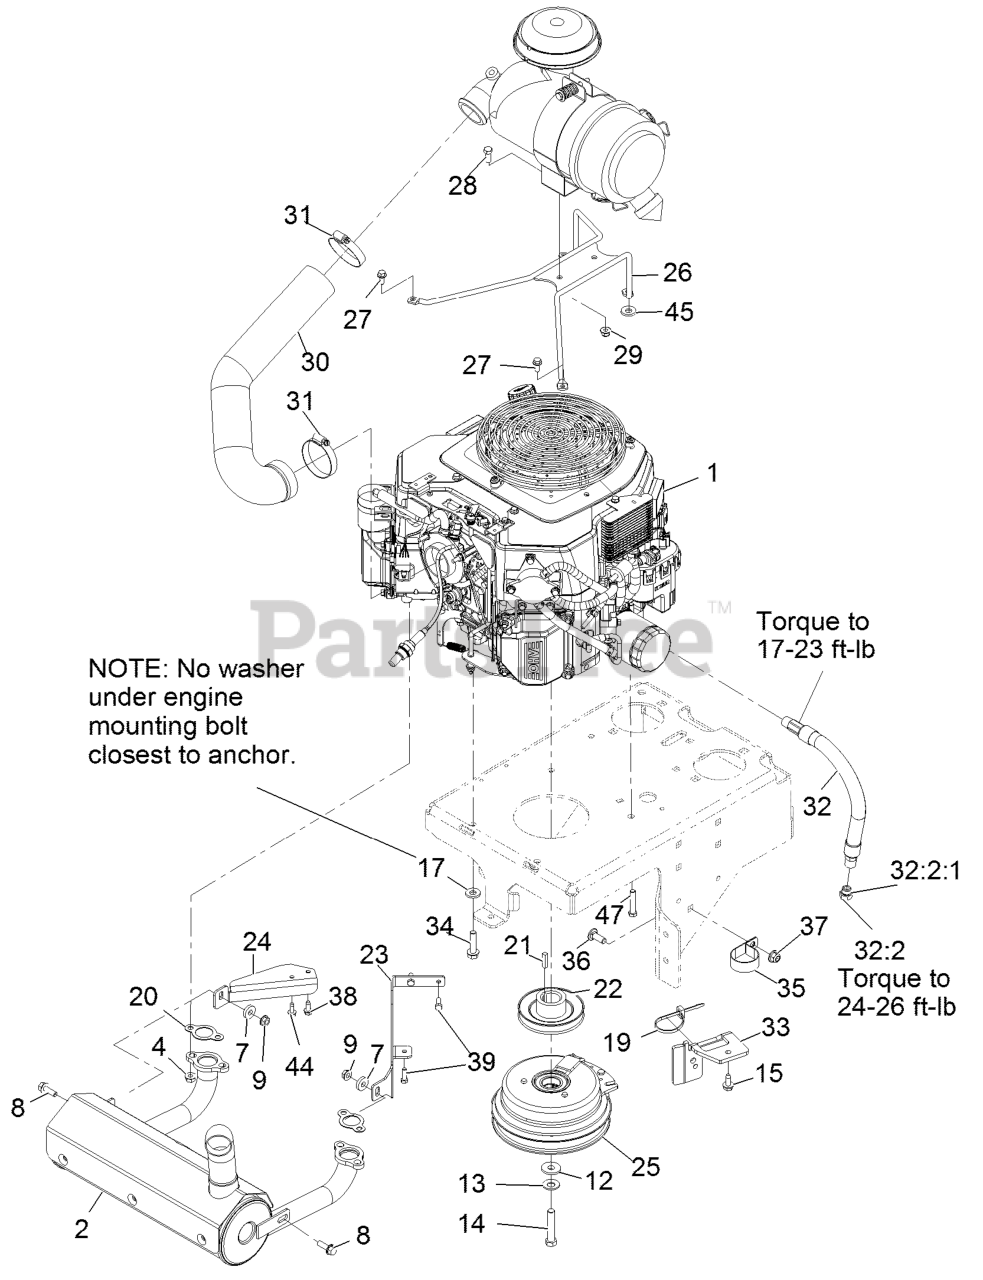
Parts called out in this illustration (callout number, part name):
1	Engine, Kohler
4	NUT-FLANGE
8	SCREW-HHF
12	WASHER
13	WASHER-SPRING
14	SCREW-HH
15	Screw-HWH 5/16-18 X 3/4 Tf
17	WASHER-BELLEVILLE
19	TIE-CABLE
20	GASKET-EXHAUST
23	BRACKET-MUFFLER, LH
24	BRACKET-MUFFLER, RH
25	CLUTCH-200 FT-LB, 1.125 B
26	MOUNT-CLEANER, AIR
27	SCREW-HHF
28	SCREW-HH
29	NUT-HF, NI
30	HOSE-INTAKE, AIR
31	CLAMP-HOSE
32	OIL DRAIN HOSE ASM
32:2	PLUG-HH
32:2:1	O-RING
33	BRACKET-ANCHOR, CLUTCH
34	SCREW-HWH
35	CLAMP-R
36	SCREW-CARR
37	NUT-HF, NI
38	SCREW-HWHTF
39	SCREW-HH M6-1 X 20Mm W/Patch
44	SCREW-HWHTF
45	WASHER-PLAIN
47	SCREW-HH
